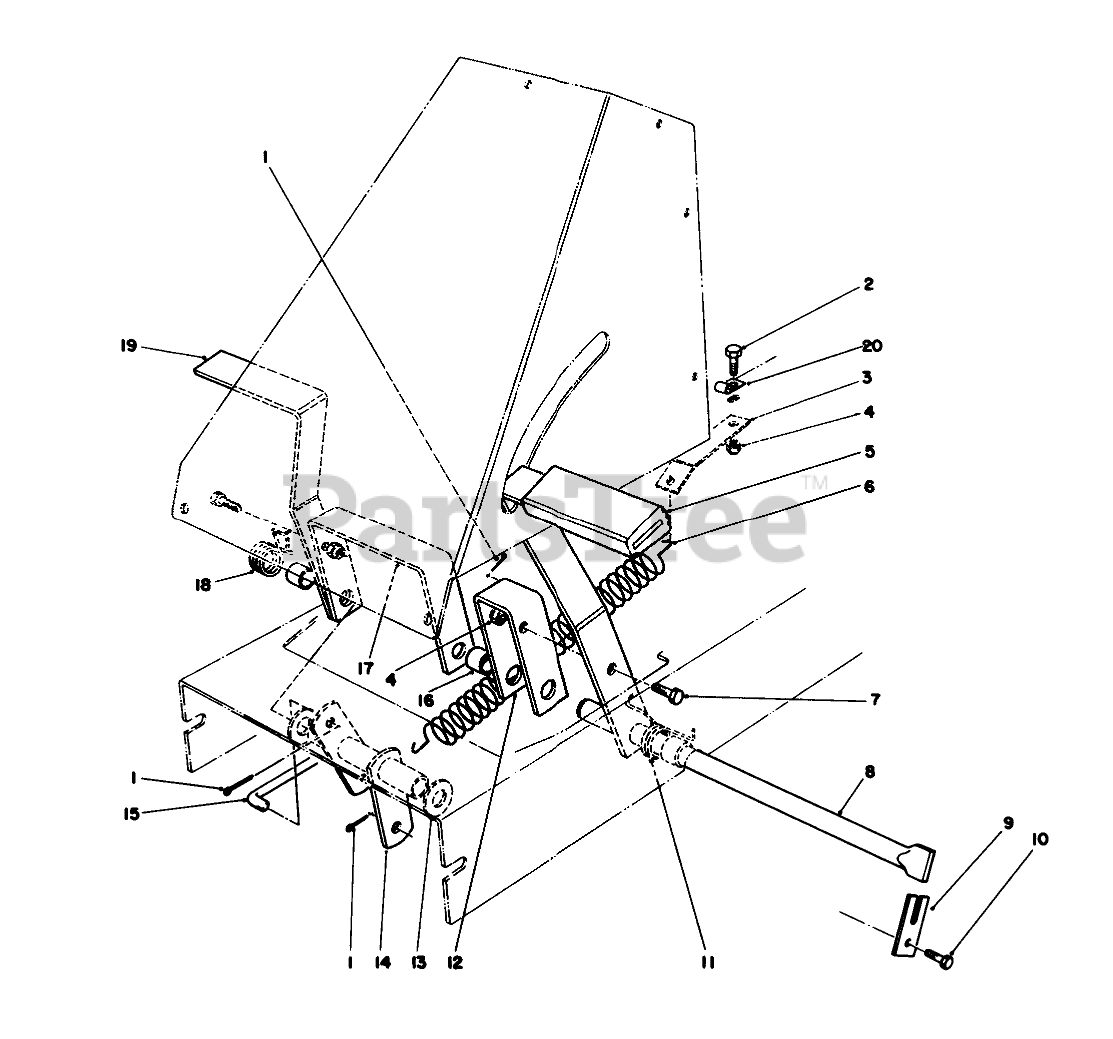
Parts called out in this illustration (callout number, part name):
1	PIN-COTTER
2	SCREW-HH
3	BRKT-SPRING RET
4	NUT-LOCK, NI
5	PAD-PEDAL
6	SPRING-EXTENSION
7	SCREW-HH
8	Shaft-Pedal Pivot
9	Arm-Engagement
10	SCREW-HH
11	SPRING-TORS CLUTCH
12	Bracket-Clutch Pedal
13	WASHER-FLAT
14	Pivot Tube
15	ROD-ENGAGE
16	SPACER-PEDAL
17	Bracket-Brake Pedal
18	SPRING-TORS BRAKE
19	Pedal
20	CLAMP
